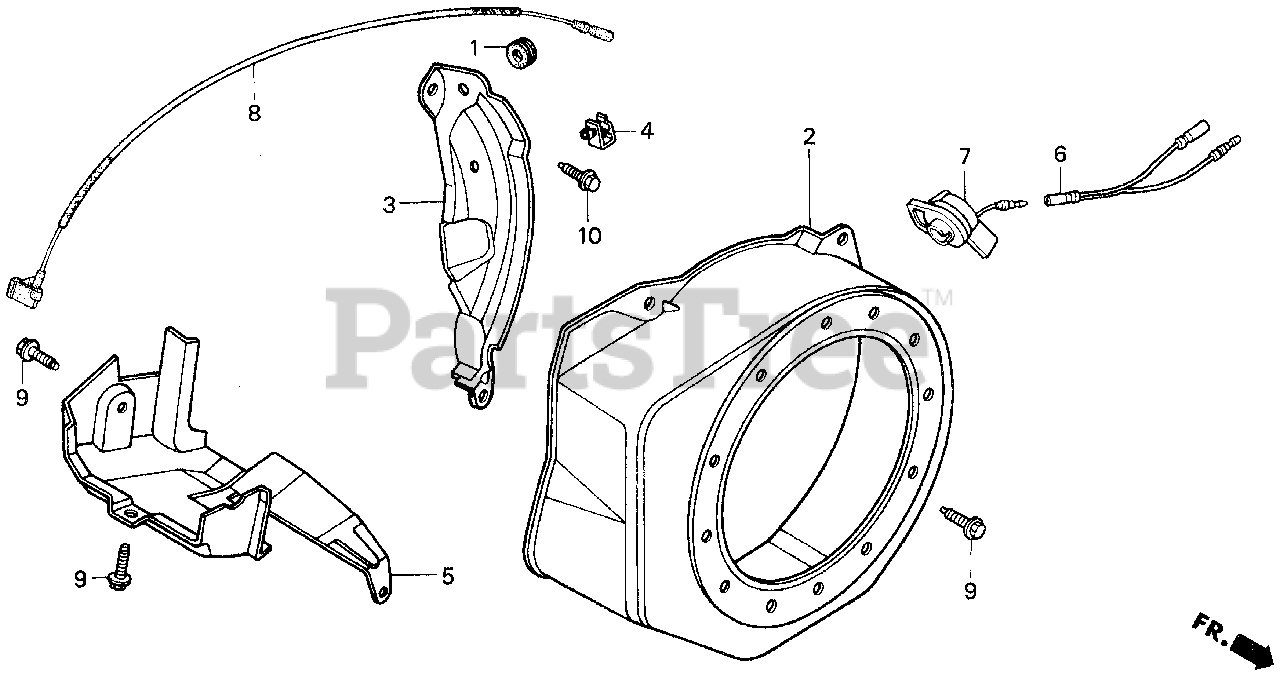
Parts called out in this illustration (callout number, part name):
1	GROMMET, ADJUSTING COVER
2	COVER, FAN *R8* (BRIGHT RED)
2	COVER, FAN *NH1* (BLACK)
3	PLATE, SIDE (STD)
5	SHROUD
7	SWITCH ASSY., ENGINE STOP
8	WIRE, STOP SWITCH (370MM)
9	BOLT, FLANGE (6X12) (CT200)
10	BOLT, FLANGE (6X20) (CT200)
